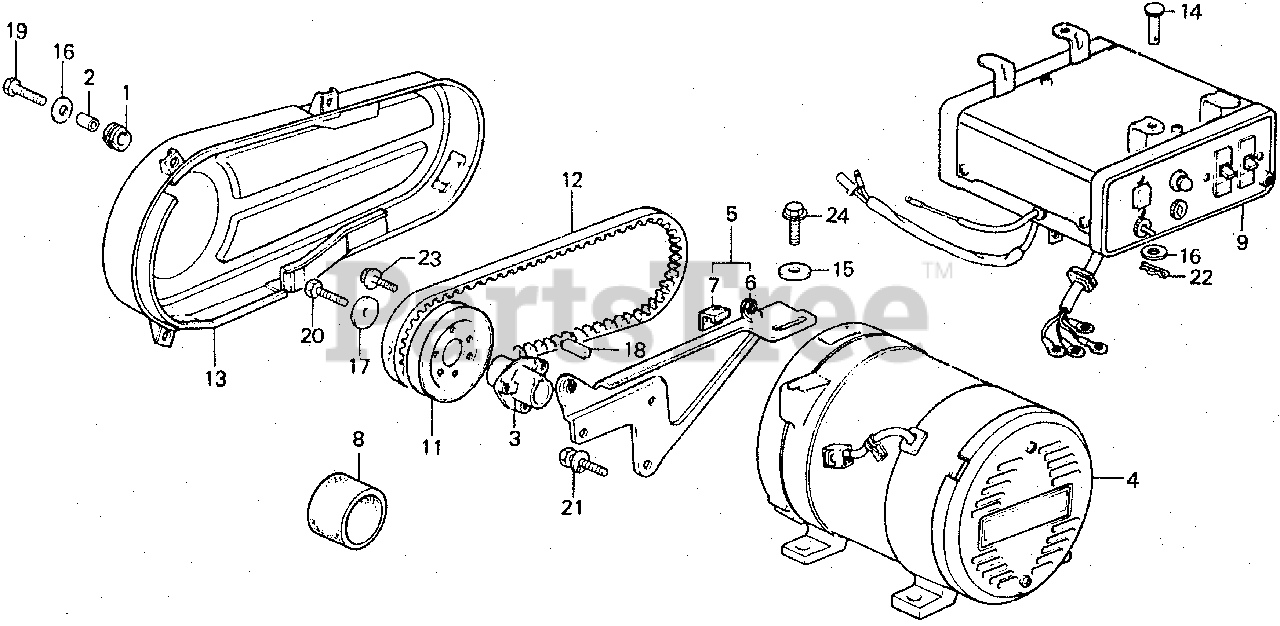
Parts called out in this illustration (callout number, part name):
1	RUBBER, TANK CUSHION (NOT AVAILABLE)
2	COLLAR, DISTANCE
3	BOSS, DRIVE PULLEY (NOT AVAILABLE)
4	GENERATOR ASSY. *R8/NH31/NH1* (BRIGHT RED/MC KINLEY WHITE/ BLACK)
5	STAY ASSY., GENERATOR (NOT AVAILABLE)
6	STAY, GENERATOR
6	STAY, GENERATOR (NOT AVAILABLE)
7	SEAT, RUBBER
8	PROTECTOR, STARTER
9	BOX ASSY., CONTROL *R8* (BRIGHT RED)
11	PULLEY (FOR 60) (NOT AVAILABLE)
13	COVER, BELT *R8* (BRIGHT RED)
13	COVER, BELT *R8* (BRIGHT RED) (NOT AVAILABLE)
14	PIN, CONTROL BOX SETTING
15	WASHER (10X30X3.5T)
16	WASHER, FLAT (20MM)
17	WASHER, LOCK (8MM)
18	KEY (7X7X33)
19	BOLT, HEX. (6X20)
20	BOLT, HEX. (8X25)
21	BOLT-WASHER (8X20)
22	PIN, LOCK (8MM)
23	BOLT, FLANGE (6X16)
24	BOLT, FLANGE (10X25)
